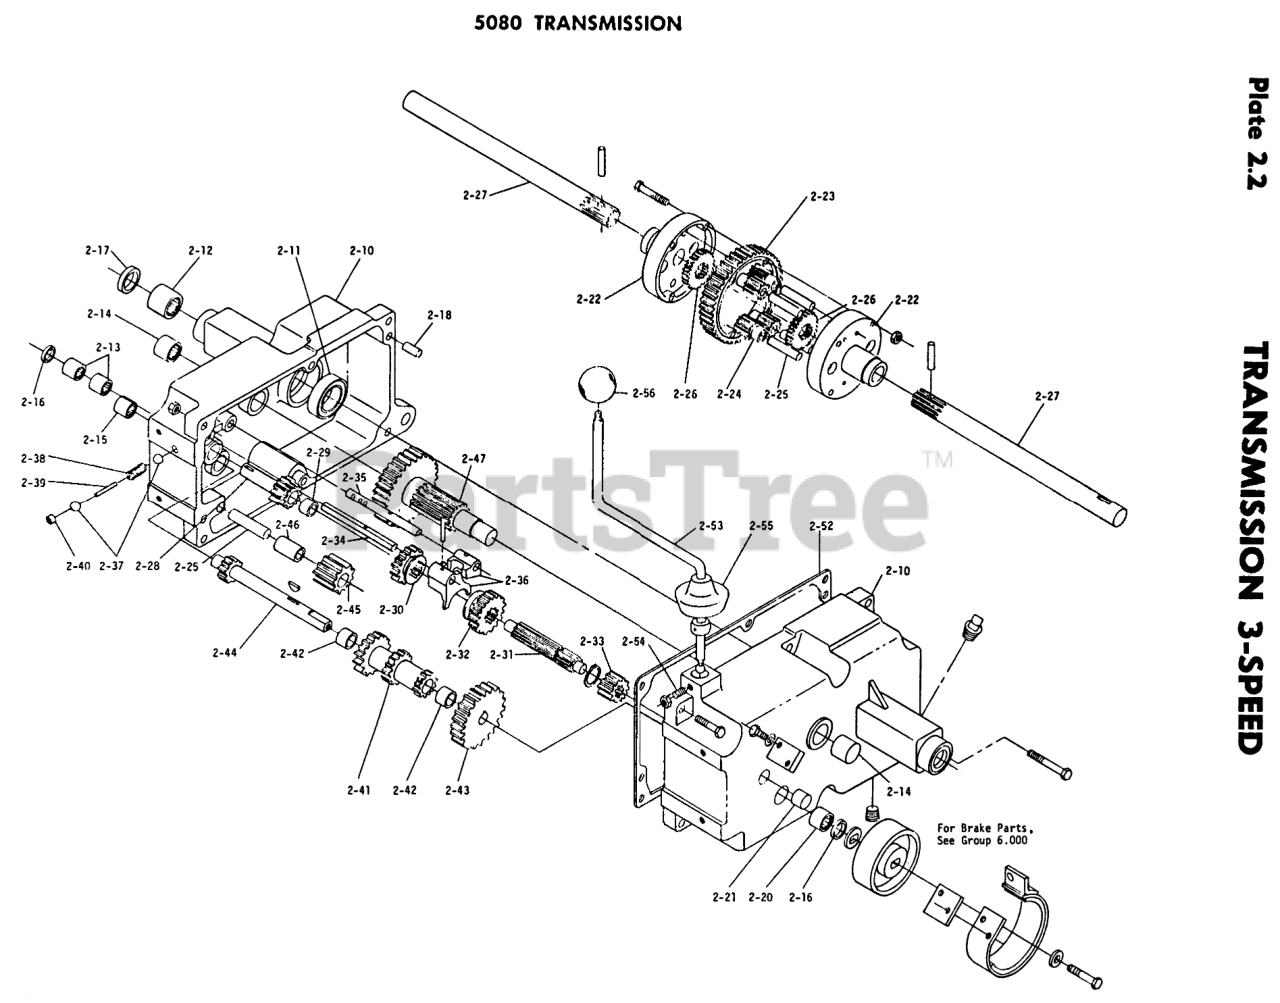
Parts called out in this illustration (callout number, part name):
2-10	Bolt Hex 3/8-16 x 1
2-10	Bolt, 3/8 16 x 2
2-12	BEARING-NEEDLE
2-14	BEARING-NEEDLE
2-15	BEARING-NEEDLE
2-16	SEAL-OIL
2-17	OIL SEAL
2-18	PIN-DOWEL
2-20	BEARING-NEEDLE
2-22	DIFFERENTIAL CASE
2-22	Nut 5/16-18
2-23	SVC BULLT 394
2-25	PIN-DIFFERENTIAL
2-26	AXLE GEAR
2-29	BEARING-NEEDLE
2-33	GEAR
2-34	RAIL-SHIFT
2-35	RAIL-REAR SHIFT
2-36	FORK-SHIFT
2-36	PIN-ROLL
2-37	BALL-DETENT
2-39	PIN-SHIFT
2-40	CUP-PLUG
2-42	BUSHING-BRONZE
2-43	GEAR-CLUSTER SHAFT
2-44	Key
2-45	GEAR/BUSHING ASM-REVERSE IDLER
2-46	BUSHING
2-52	GASKET-TRANSMISSION
2-54	SETSCREW
2-54	Nut 1/4-20
2-55	COVER-DUST
